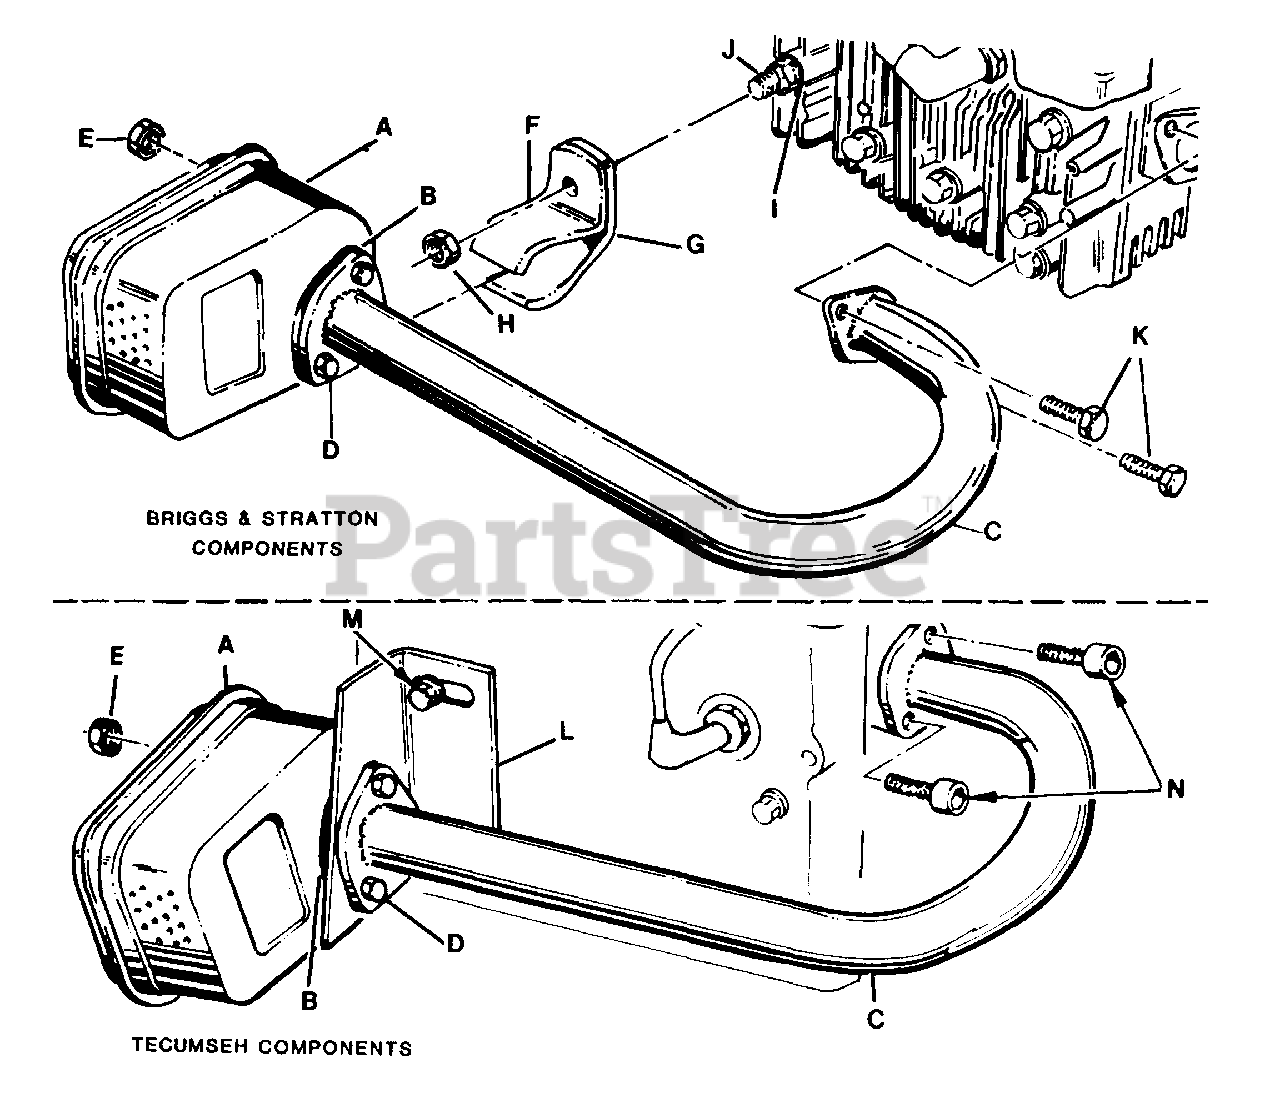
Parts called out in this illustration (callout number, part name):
A	MUFFLER
C	TUBE, EXHAUST
D	CAPSCREW, 5/16C x 3" HEX HEAD
E	LOCKNUT, 5/16C HEX
F	CLIP, TOP
G	CLIP, BOTTOM
H	NUT, 5/16-18 HEX
I	WASHER, FLAT
J	STUD, CYLINDER HEAD
K	CAPSCREW, 1/4-20 x 5/8 HEX HEAD
L	CLIP, MOUNTING
M	SCREW, 1/4C x 5/8 SELF-TAPPING
N	SETSCREW, 5/16C x 3/4 FLANGE
